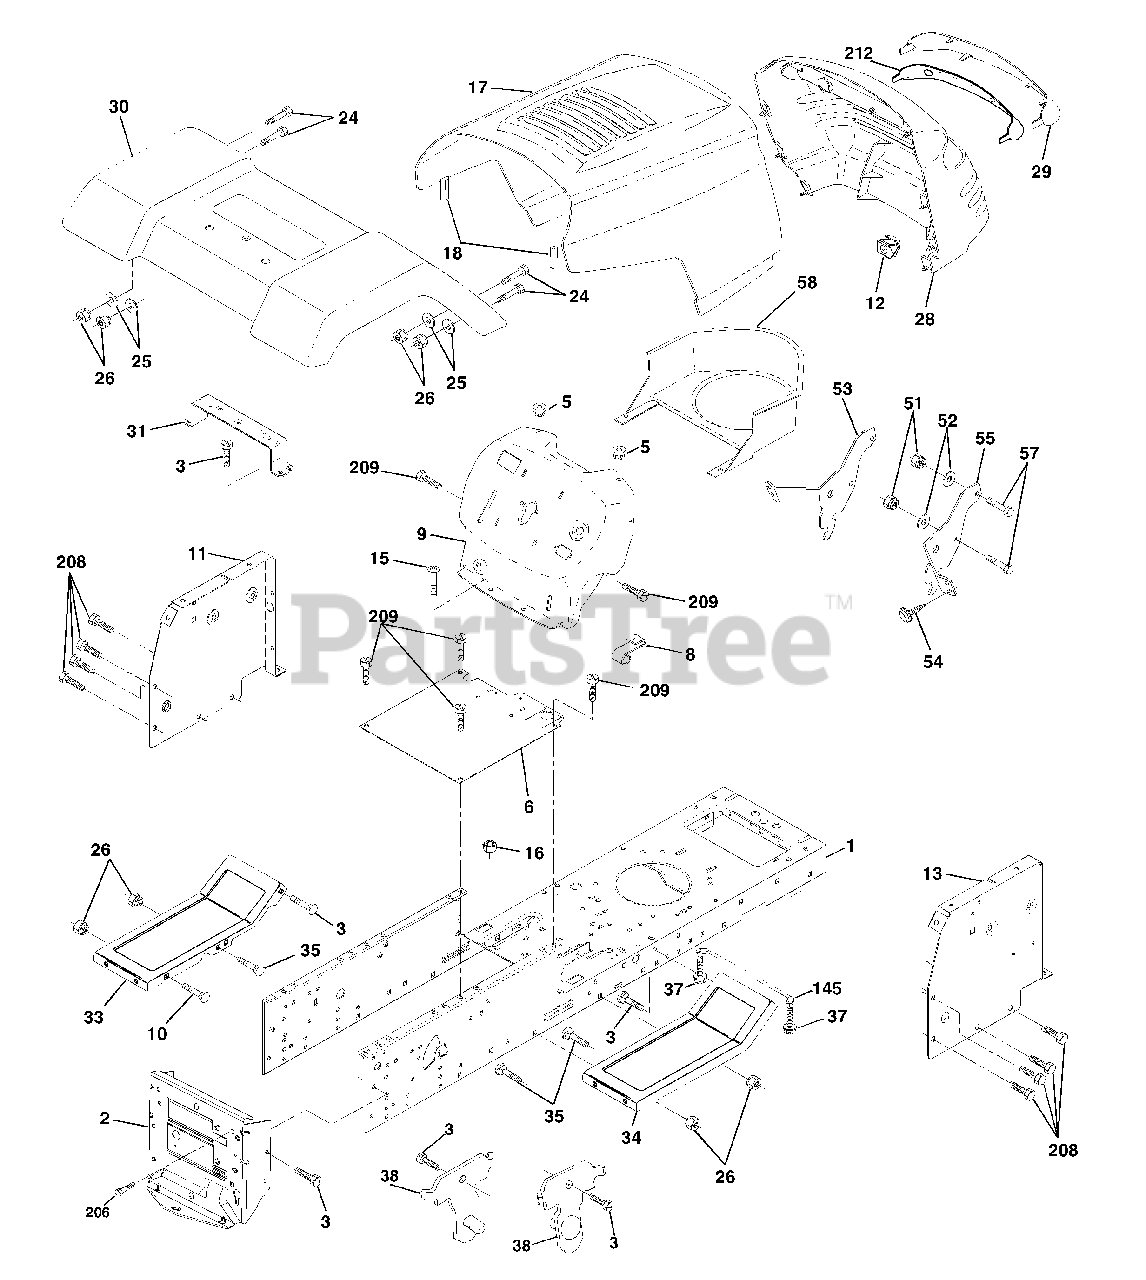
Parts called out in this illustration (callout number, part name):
2	Drawbar
3	Screw 3/8-16 x 3/4
5	Bumper Hood/Dash
6	Saddle Slkscr Flat Lt 6 Sp
8	Clip Retainer Slide-On
9	Dash
10	Bolt Rd Hd Sqnk. 3/8-16 Unc x 1
11	Panel Asm. Dash Lh
12	Clip Tinnerman Grile P/L
15	Screw Mach Trhd 5/16-18 Unc x 3/4
16	Nut Keps 5/16-18 Unc
17	Hood
18	Bumper Hood
24	Bolt Fin Hex 3/8-16 Unc x 1 Gr. 5
25	Washer 13/32 x 13/16 x 12 Ga.
26	Nut Lock Hex w/Insert 3/8-16 UNC
28	Grill/Lens Asm
29	Lens Grille Private label
30	Fender Asm
31	Bracket Fender
33	Footrest
34	Footrest
35	Bolt Rd Hd Sht. Sqnk. 3/8-16 x 3/4
37	Screw Thdrol 5/16-18 x 1/2 Tyt
38	Bracket Asm. Pivot Mower Rear
51	Nut Lock Hex W/Ins. 1/4-20
52	Washer 9/32 x 7/8 x 16 Ga.
53	Bracket Grille LH
54	Screw Hex Wshd 8-18 x 7/8
55	Bracket, Grille RH
57	Bolt Fin Hex 1/4-20 x .75
58	Air Duct Private Label
145	Rod Pivot Chassis/Hood
206	Bolt shoulder 5/16-18
208	Screw Thdrol 3/8-16 x 1/2
209	Screw Hex Wsh Thdrol 3/8-16
212	Insert Lens Reflector
